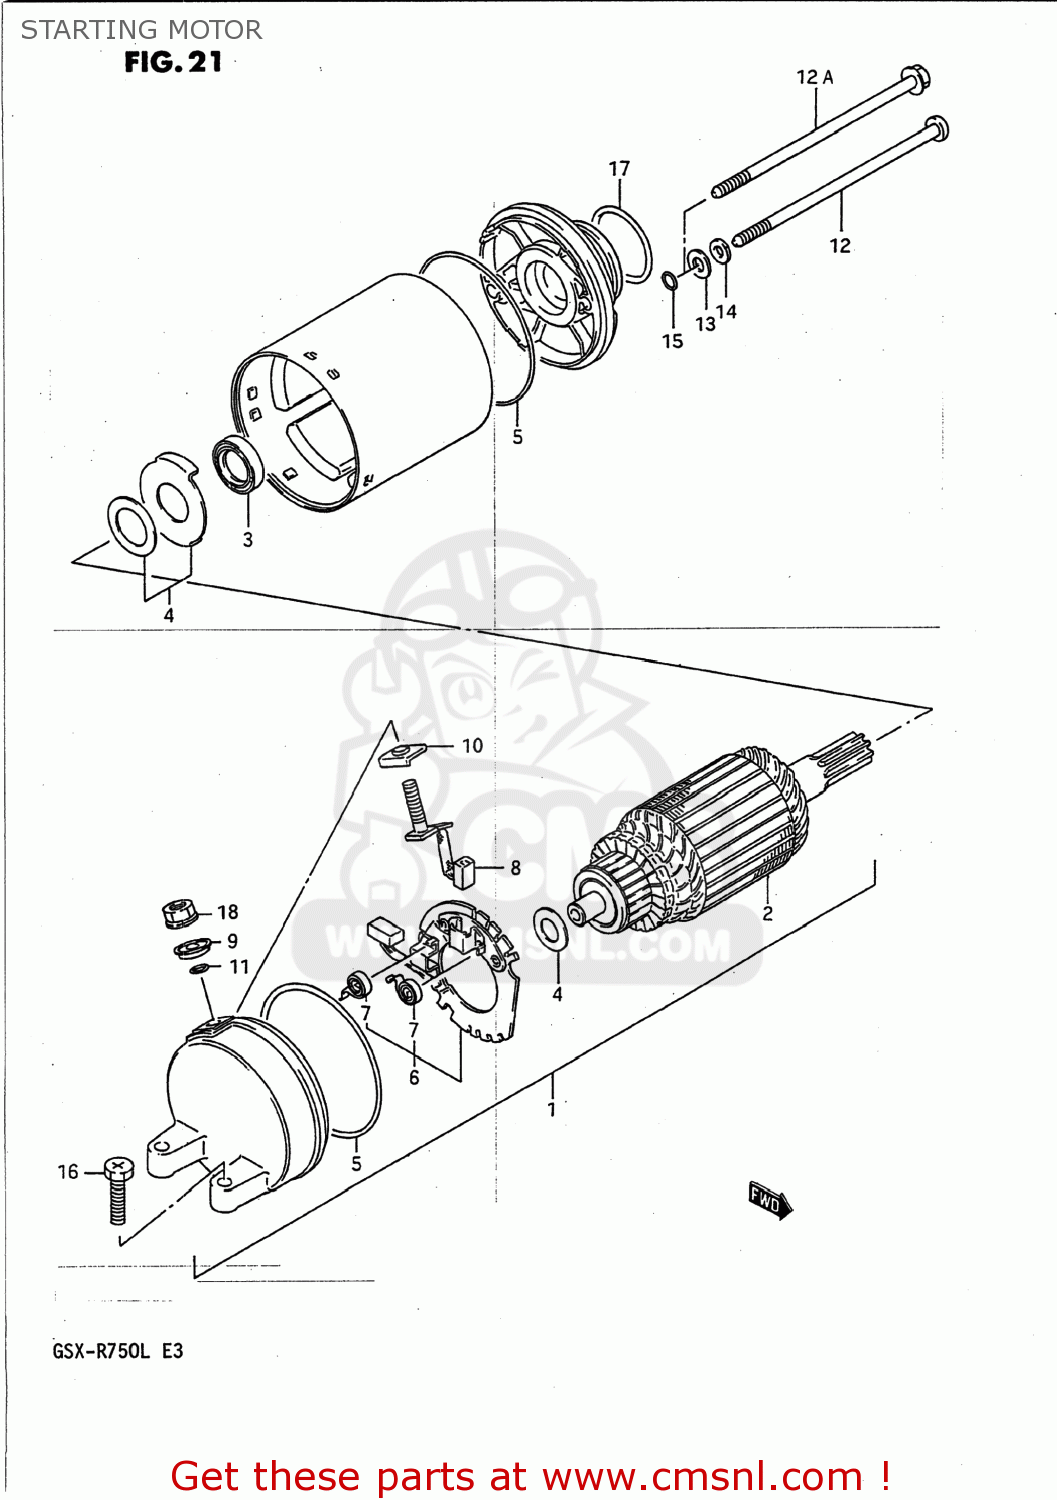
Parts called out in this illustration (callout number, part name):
1	MOTOR ASSEMBLY,STARTING
2	ARMATURE
3	SEAL,OIL
4	SHIM SET,STARTING MOTOR
5	O RING
6	HOLDER,BRUSH
7	SPRING
8	BRUSH SUB ASSY,STARTING MOTOR
9	BUSHING
10	BUSH,B
11	O RING
12	BOLT
12A	BOLT
13	WASHER
14	WASHER,LOCK
15	O RING
16	SCREW (6X25)
17	O RING(D:3,ID:24.5)
18	NUT
